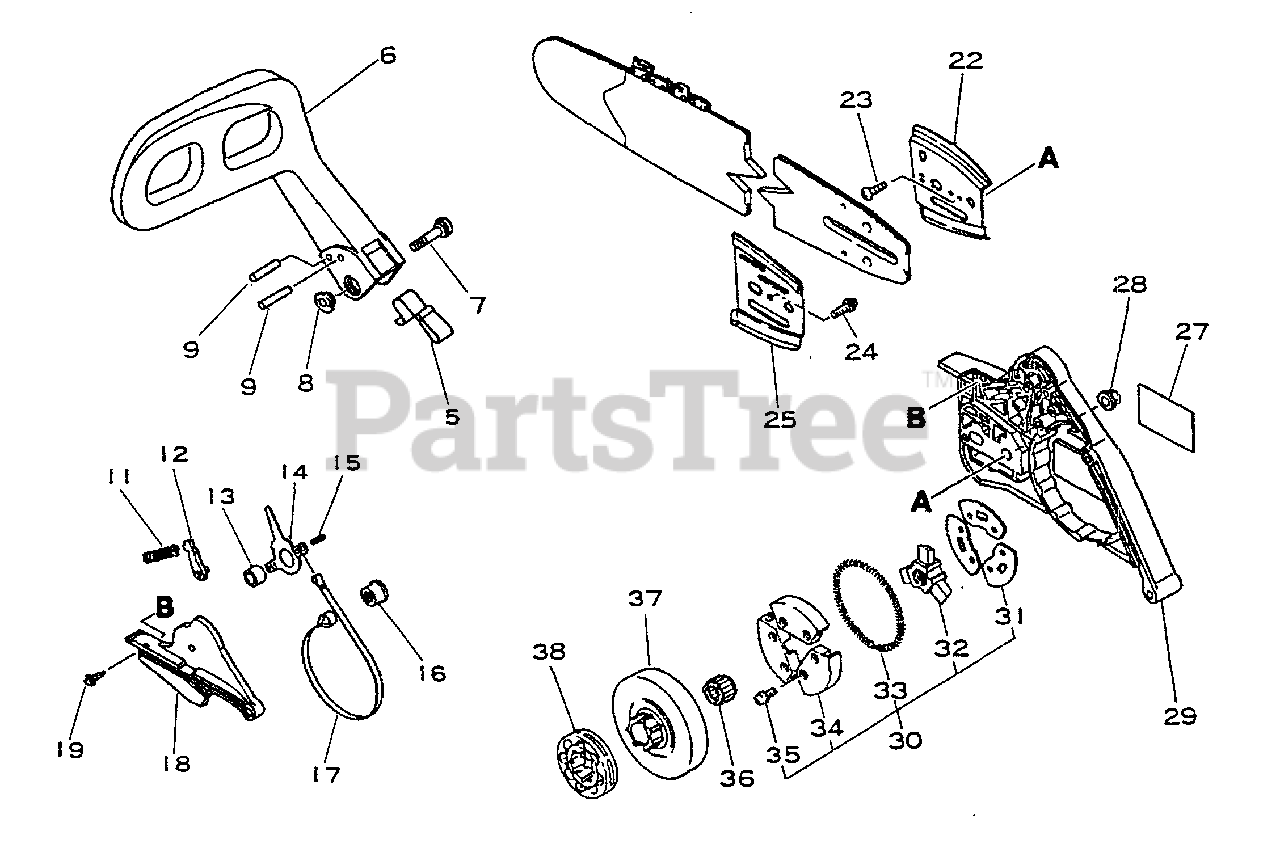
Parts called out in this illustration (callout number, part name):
5	SPRING, RETURN
6	LEVER, BRAKE
7	MOUNTING KIT
9	PIN - 3.5X26
11	SPRING, BRAKE
12	STOPPER, BRAKE
13	SPACER - 8
14	LEVER, BRAKE
15	PIN - SPRING
16	ADJUSTER, BRAKE BAND
17	BAND, BRAKE
18	COVER, BRAKE
19	SCREW - 4X10
22	PLATE, GUIDE - OUTER
23	SCREW - 4X8
24	SCREW - 3X6
25	PLATE, GUIDE - INNER
27	LABEL - ECHO
28	NUT - FLANGE
29	GUARD, SPROCKET
30	CLUTCH ASSY
31	PLATE, CLUTCH
32	HUB, CLUTCH
33	SPRING, CLUTCH
34	CLUTCH SHOE SET
35	SCREW - 4X8
36	BEARING, NEEDLE
37	DRUM, CLUTCH
38	SPROCKET, RIM
